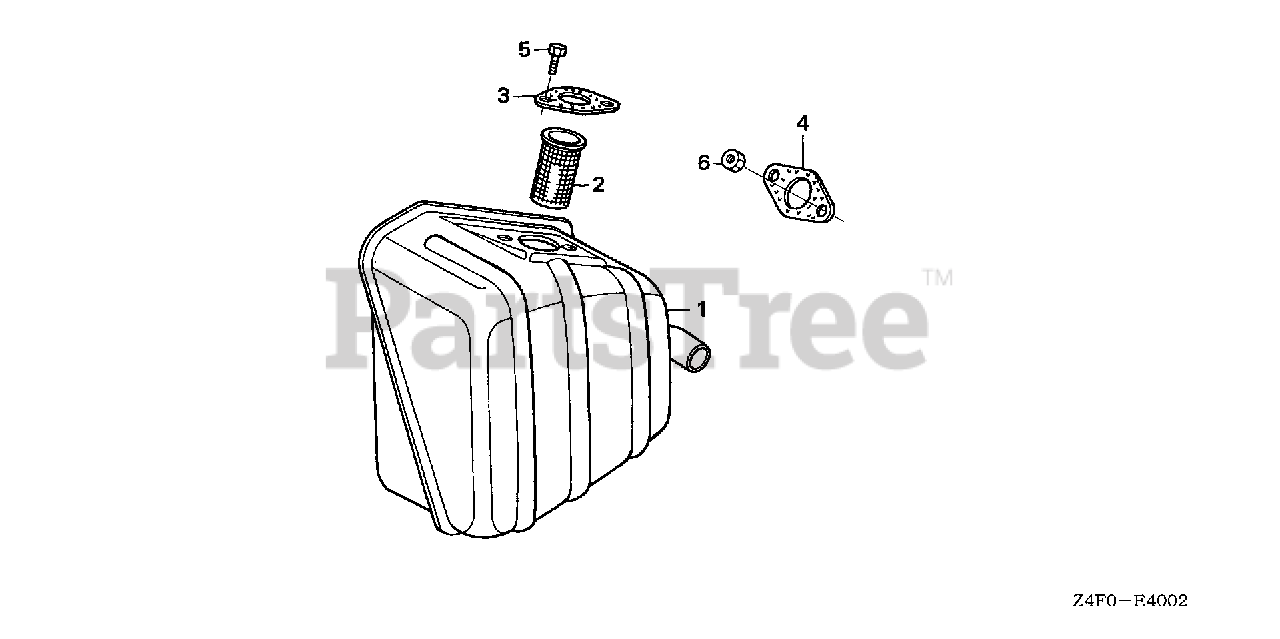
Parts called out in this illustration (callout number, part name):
2	ARRESTER, SPARK
3	GASKET, MUFFLER
4	GASKET, MUFFLER
5	BOLT, HEX. (8X20)
6	NUT, HEX. (8MM)
